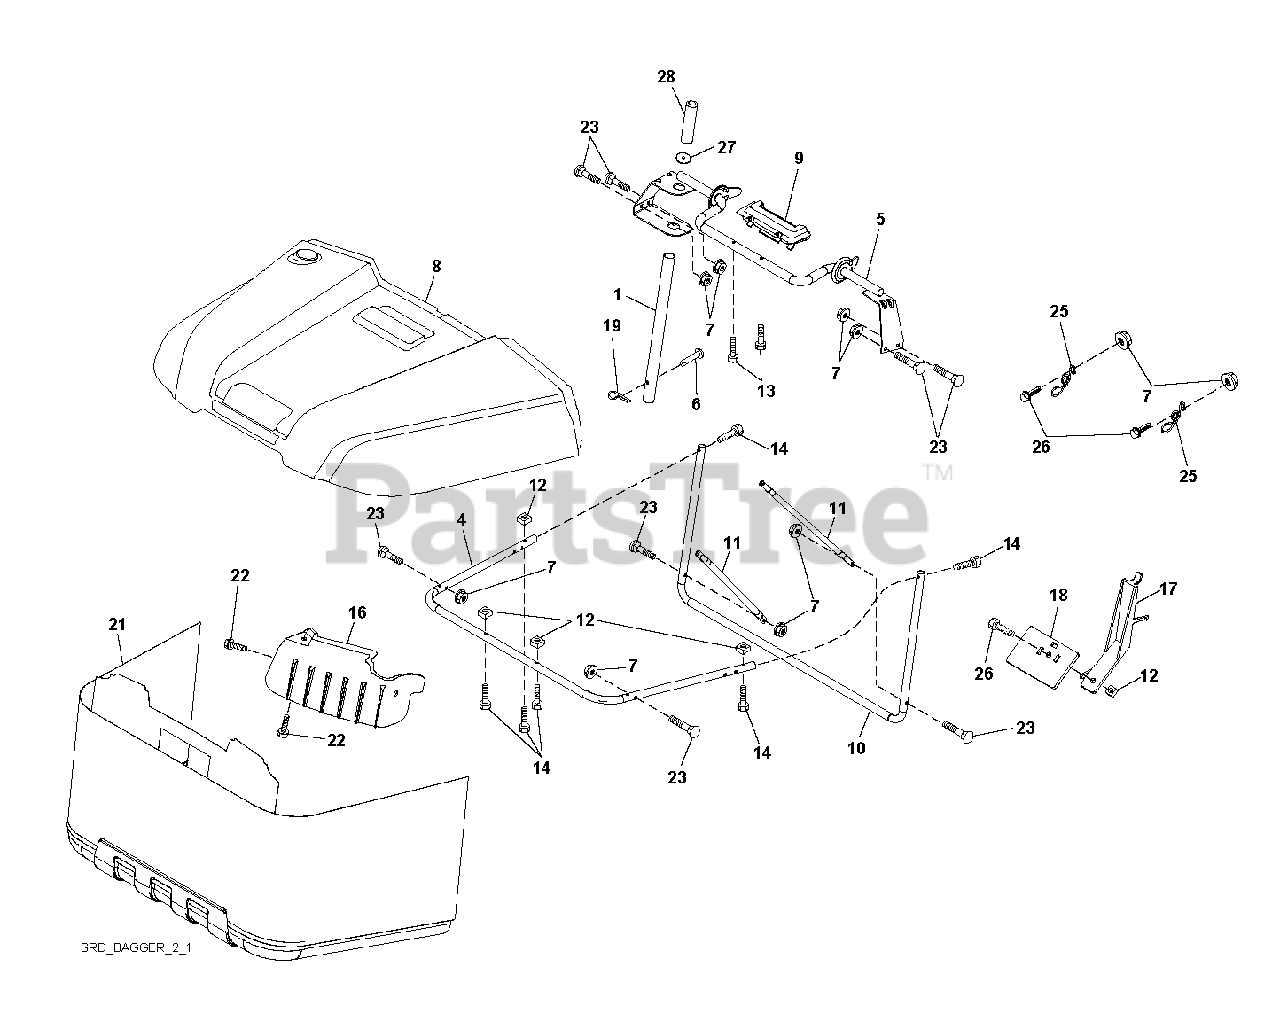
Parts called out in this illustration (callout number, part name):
1	TUBE.PNT.HDL.BAGGER.
5	FRAME.ASM.TOP.BAGGER.SRD
6	RIVET,DRILLED
7	NUT T
8	COVER.BAGGER.SRD.BLACK
9	INSERT.HANDLE.BAGGER.(2 2)
10	FRAME.FRONT.SRD.BAGGER
11	TUBING.BRACE.BAGGER.SRD.BLACK
12	NUT.SQUARE.1/4
13	SCREW.1/4X1.150.HXWSH
14	BOLT.SHOULDER.HX.WSH.1/4X1.150
16	DEFLECTOR.BAGGER.SRD
17	Bagger Lever, Full SRD Black
18	PADDLE.BAGGER.FULL.SRD.BLACK
19	PIN.COTTER.5/16.BOW TI
22	SCREW.HI-LO.CONSOLE
25	SPRING.LATCH.BAGGER.SRD
26	SCREW HEX CRT
27	GROMMET.RUBBER.SRD
28	GRIP.HANDLE.BLACK
